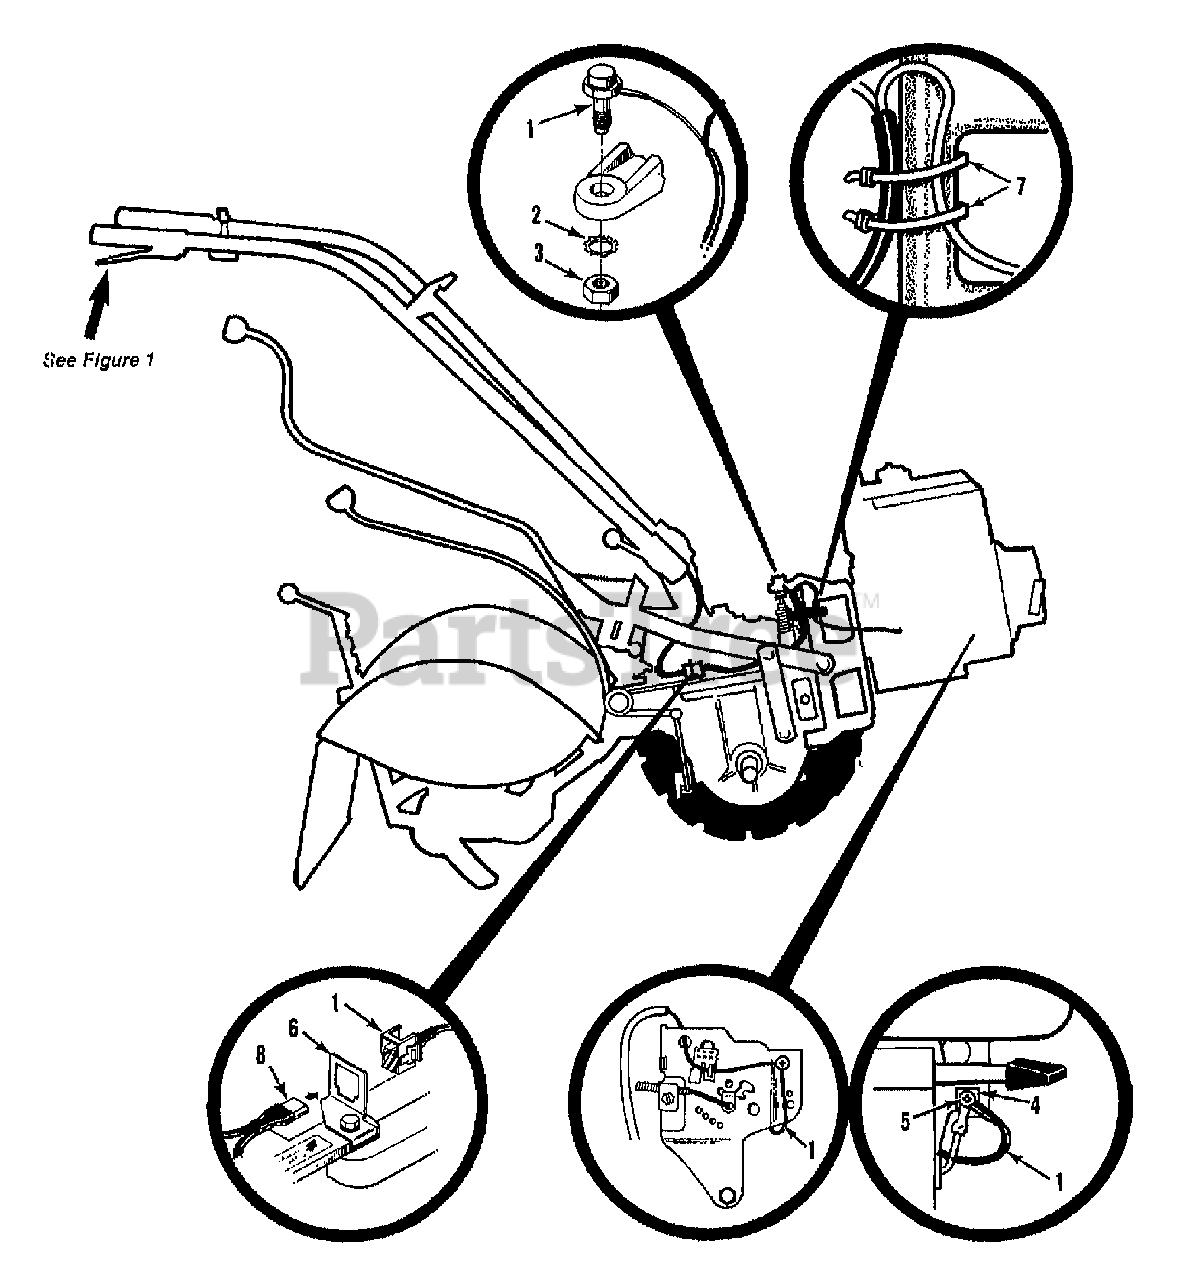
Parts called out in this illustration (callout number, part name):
1	HARNESS-WIRE ENG OPC
2	WASHER-LK .438 EXT TOOTH
3	NUT-HEX/JAM 7/16-20
4	GROMMET-7 T/L & 8 KOH OPC
5	SCR #8-18 SELF TAP
6	CLIP-CONNECTOR
7	TIE-RED
8	HARNESS-WIRE OPC HORSE
